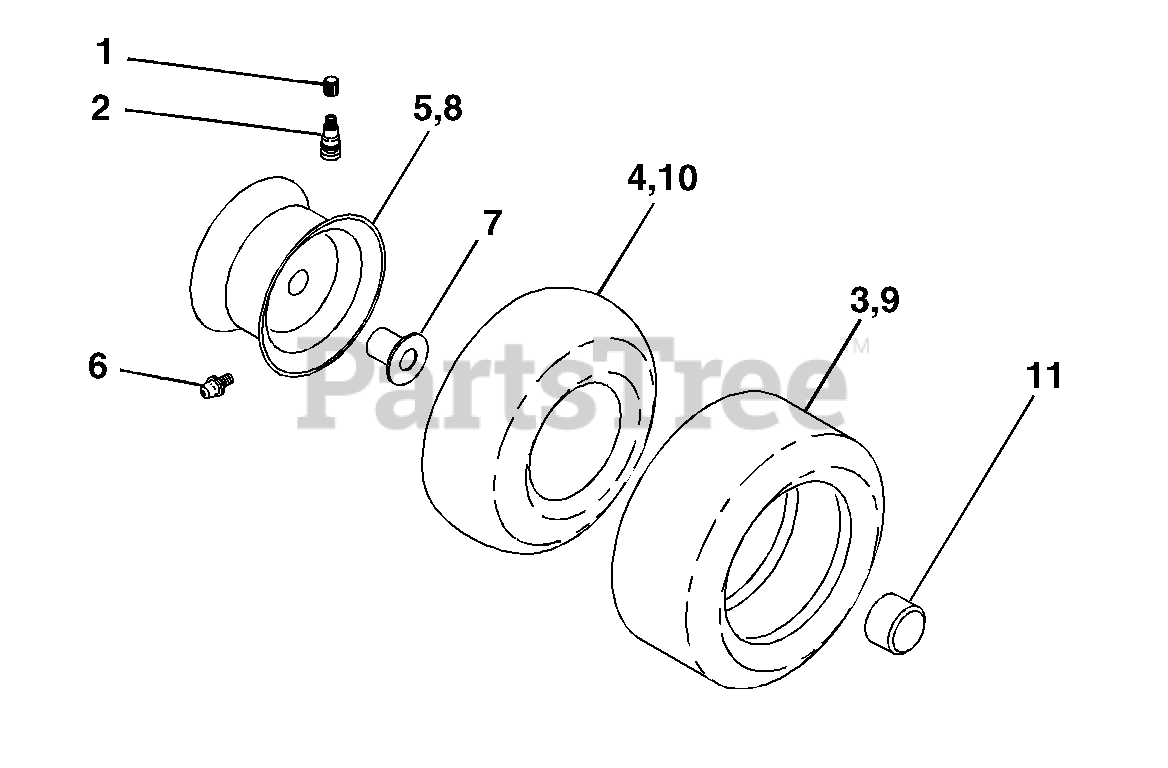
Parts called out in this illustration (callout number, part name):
1	Cap Valve Tire
2	Stem Valve
3	Tire F Ts 15 X 6 0 - 6 Service
4	Tube Front
5	Rim Asm 6"front Silver Service
6	Fitting Grease
7	Bearing Flange
8	Rim Asm 8"rear Silver Service
9	Tire R Ts 20x10-8 C Service
10	Tube Rear
11	Cap Axle Blk 1 50 X 1 00
